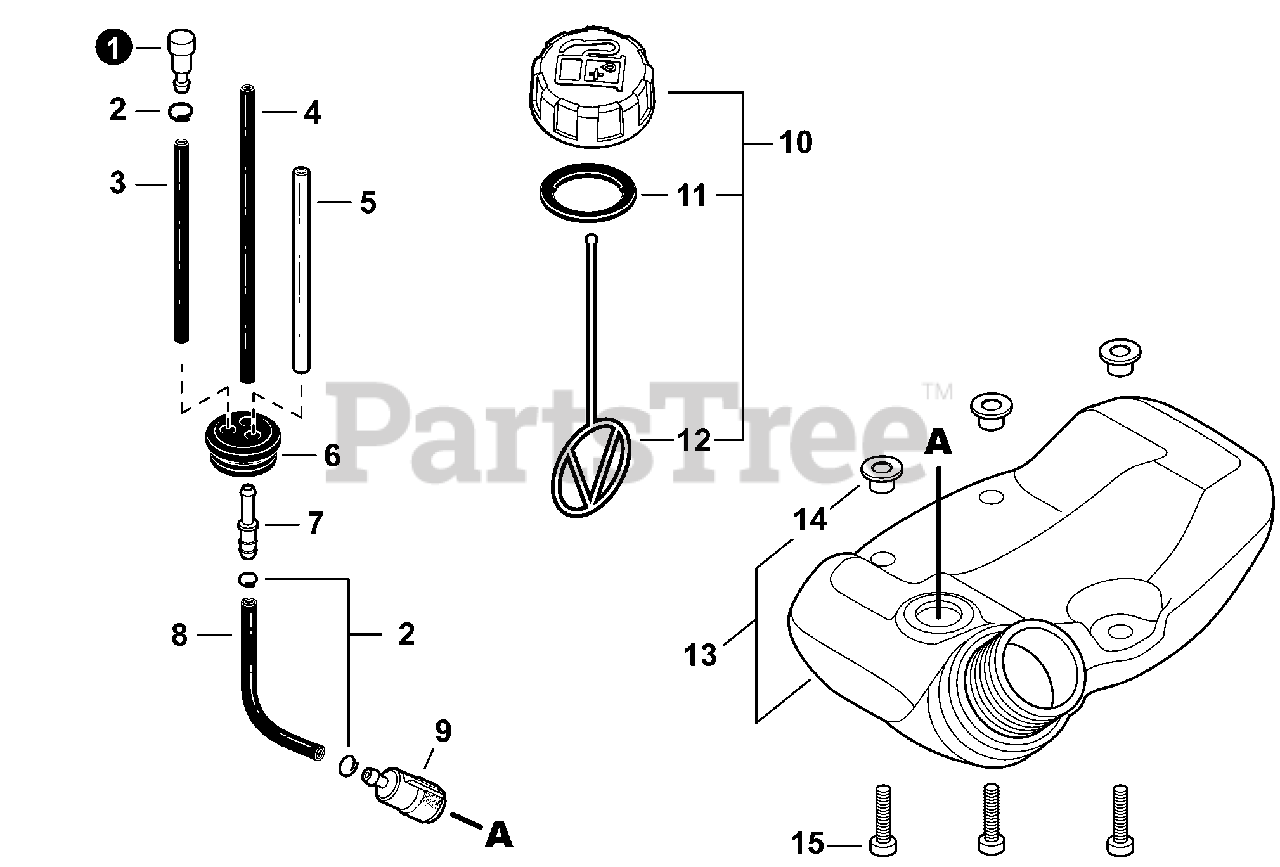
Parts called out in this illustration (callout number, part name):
1	VENT ASSY
2	CLIP Ø6
3	PIPE, FUEL 3×5×90 BLACK
4	PIPE, FUEL 3×5×74 BLACK
5	PIPE, FUEL 3×6×80 CLEAR
6	GROMMET, FUEL Ø5
7	CONNECTOR, PIPE Ø5ר3.5
8	PIPE, FUEL 3×5×130 BLACK
9	FILTER, FUEL
10	CAP ASSY, FUEL
11	GASKET, FUEL CAP
12	CONNECTOR, CAP L= 123
13	TANK ASSY, FUEL
14	COLLAR 5
15	BOLT, TORX 5×20
